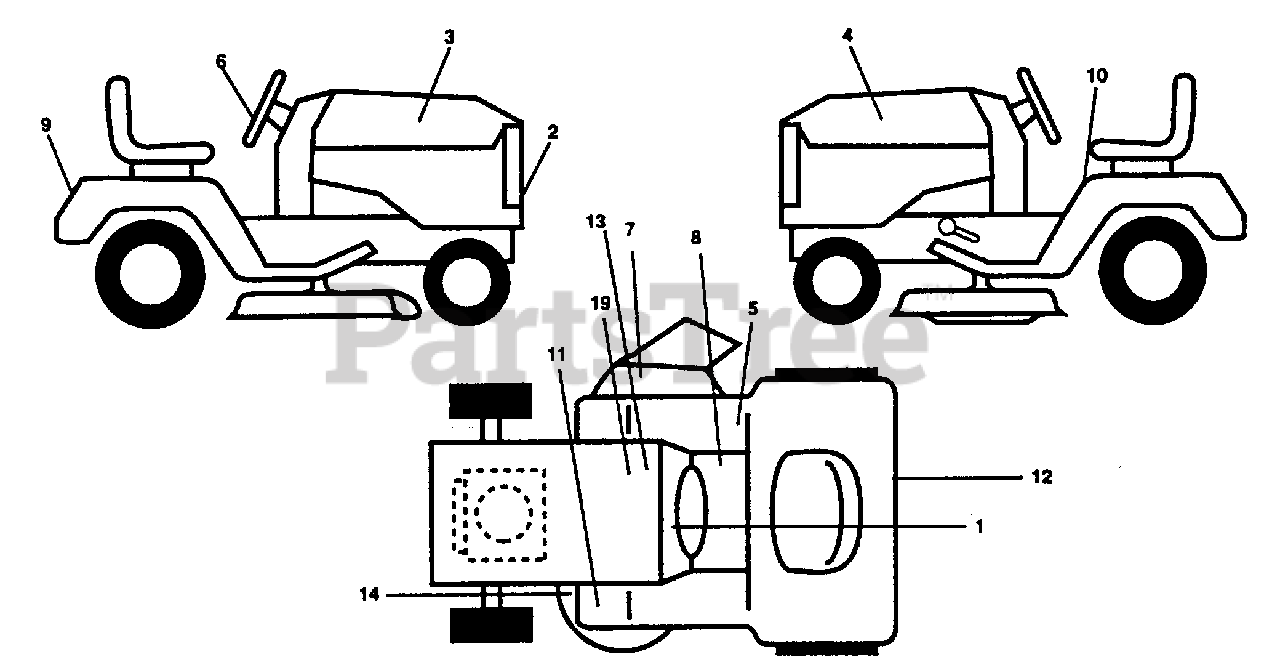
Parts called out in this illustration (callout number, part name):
1	Decal, Operating Instruction
2	Decal, Grille
3	Decal, Hood, RH
4	Decal, Hood, LH
5	Decal, Insert Strg Whl
6	Decal, Scl Cold Start Hyd
7	Decal, Warning Multi-Language
8	Decal, Brake Parking Saddle
9	Decal, Fender
10	Decal, Caution
11	Decal, Clutch/Brake
12	Decal, D-Bar Ctrl. Mvt Hyd YT/GT
13	Decal, Bat. DAN/POI P/L Symbols
14	Decal, V-Belt Schematic
19	Decal, Battery
